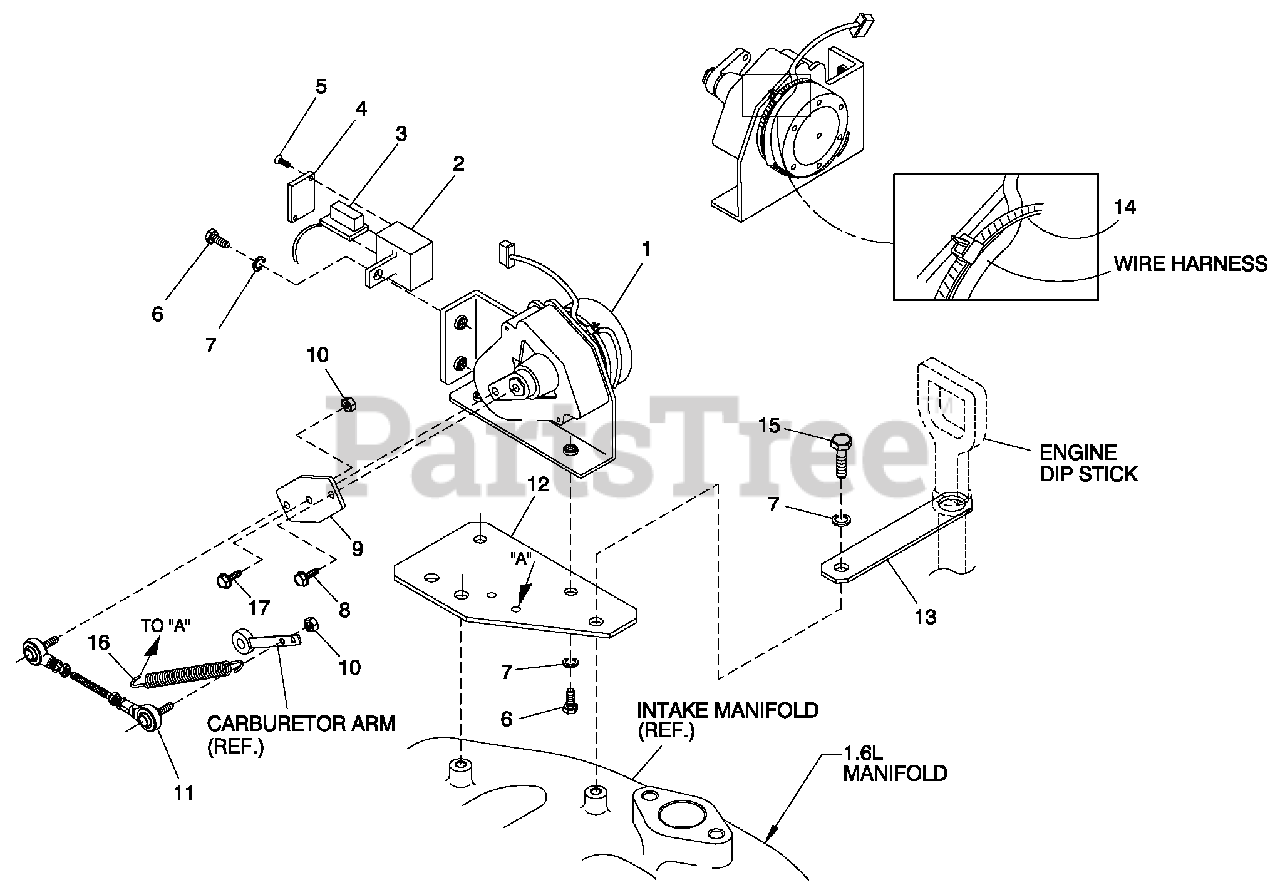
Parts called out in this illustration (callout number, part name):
1	ASM MOTOR STEPPER
2	HOUSING GOVERNOR CONNECTOR
3	CONNECTOR INTERFACE ASSEMBLY
4	COVER CONNECTOR HOUSING
5	SCREW FHM #2 X 5/8 SELF TAP
6	SCREW HHC M6-1.0 X 10 G8.8
7	WASHER LOCK M6-1/4
8	SCREW PHM M3-0.5 X 12MM
9	LEVER STEPPER MOTOR
10	NUT LOCK HEX #10-32 NYL INS
11	ASSY. CARBURETOR LINKAGE ROD
12	BRACKET STEPPER MOTOR
13	OIL DIP-STICK BRACKET 1.6L
14	TIE WRAP 7.4"X.19" BLK UL
15	SCREW HHC 1/4-20 X 1/2 G5
16	SPRING ANTI LASH
17	SCREW TAP HWH #6-25 X 3/8 ZINC
